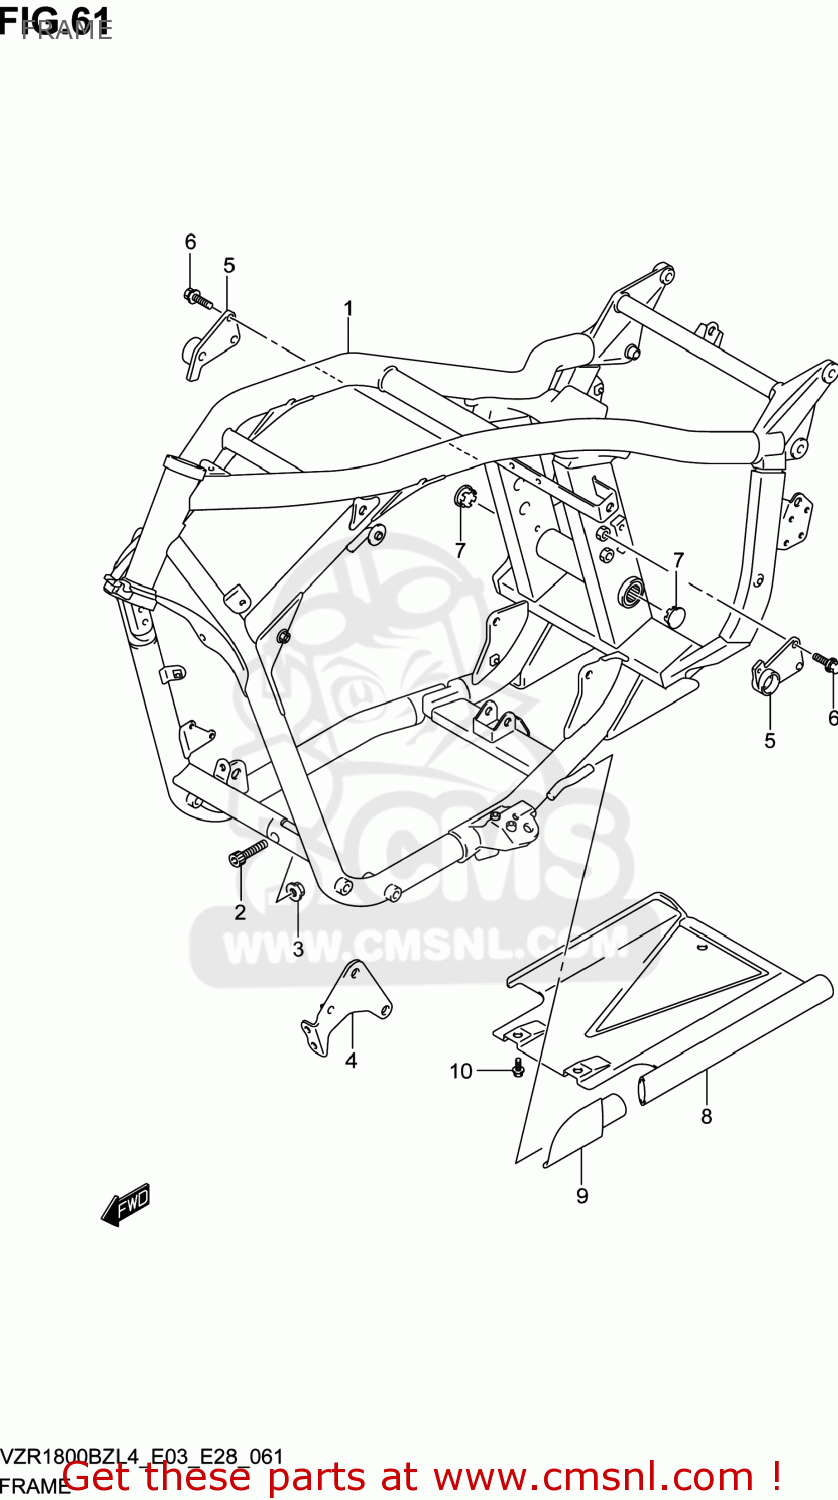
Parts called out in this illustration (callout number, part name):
1	FRAME(BLACK)
2	BOLT
3	NUT
4	PLATE,ENG MTG FR,L
5	BRACKET,ENGINE MOUNTING RR
6	BOLT
7	CAP,ENG MTG BOLT
8	COVER,UNDER
9	RUBBER,UNDER COVER
10	BOLT
